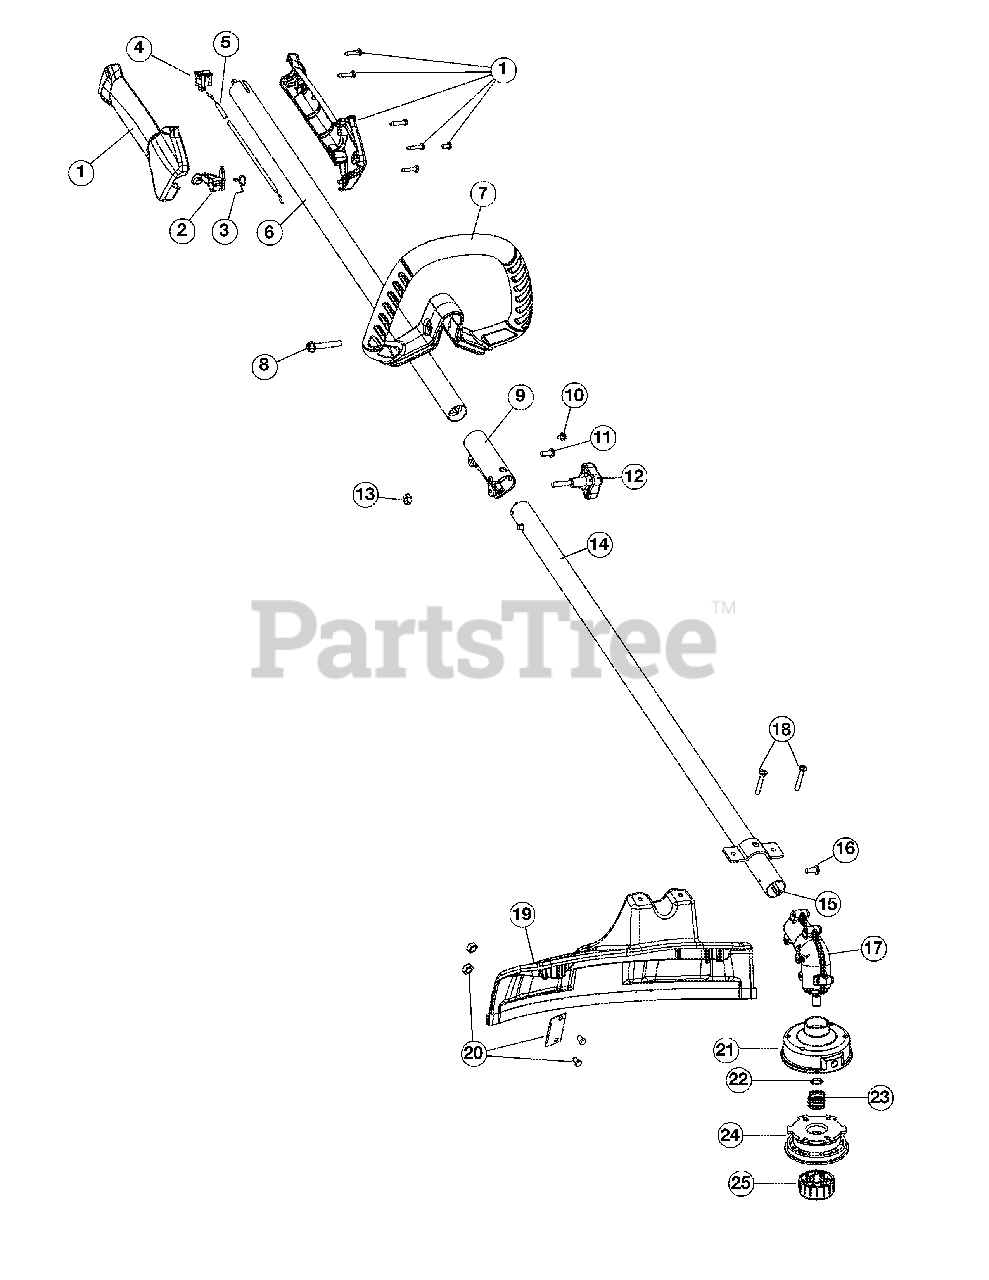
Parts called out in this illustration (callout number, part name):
1	Throttle Housing Assembly
2	Throttle Trigger
3	Throttle Trigger Spring
5	Throttle Cable Assembly
6	Upper Drive Shaft Housing Assembly
7	Deluxe D-Handle Assembly
9	Split Boom Coupler
12	Adjustment Knob
13	Knob Retaining Nut
14	Lower Drive Shaft Housing Assembly
15	Lower Flexible Drive Shaft
16	Anti-Rotation Screw
17	Gear Box Assembly
18	Shield Mounting Screws
19	Shield Assembly
20	Blade Assembly
21	Outer Spool Assembly
22	Retainer
24	Inner Reel
25	Bump Knob Assembly
